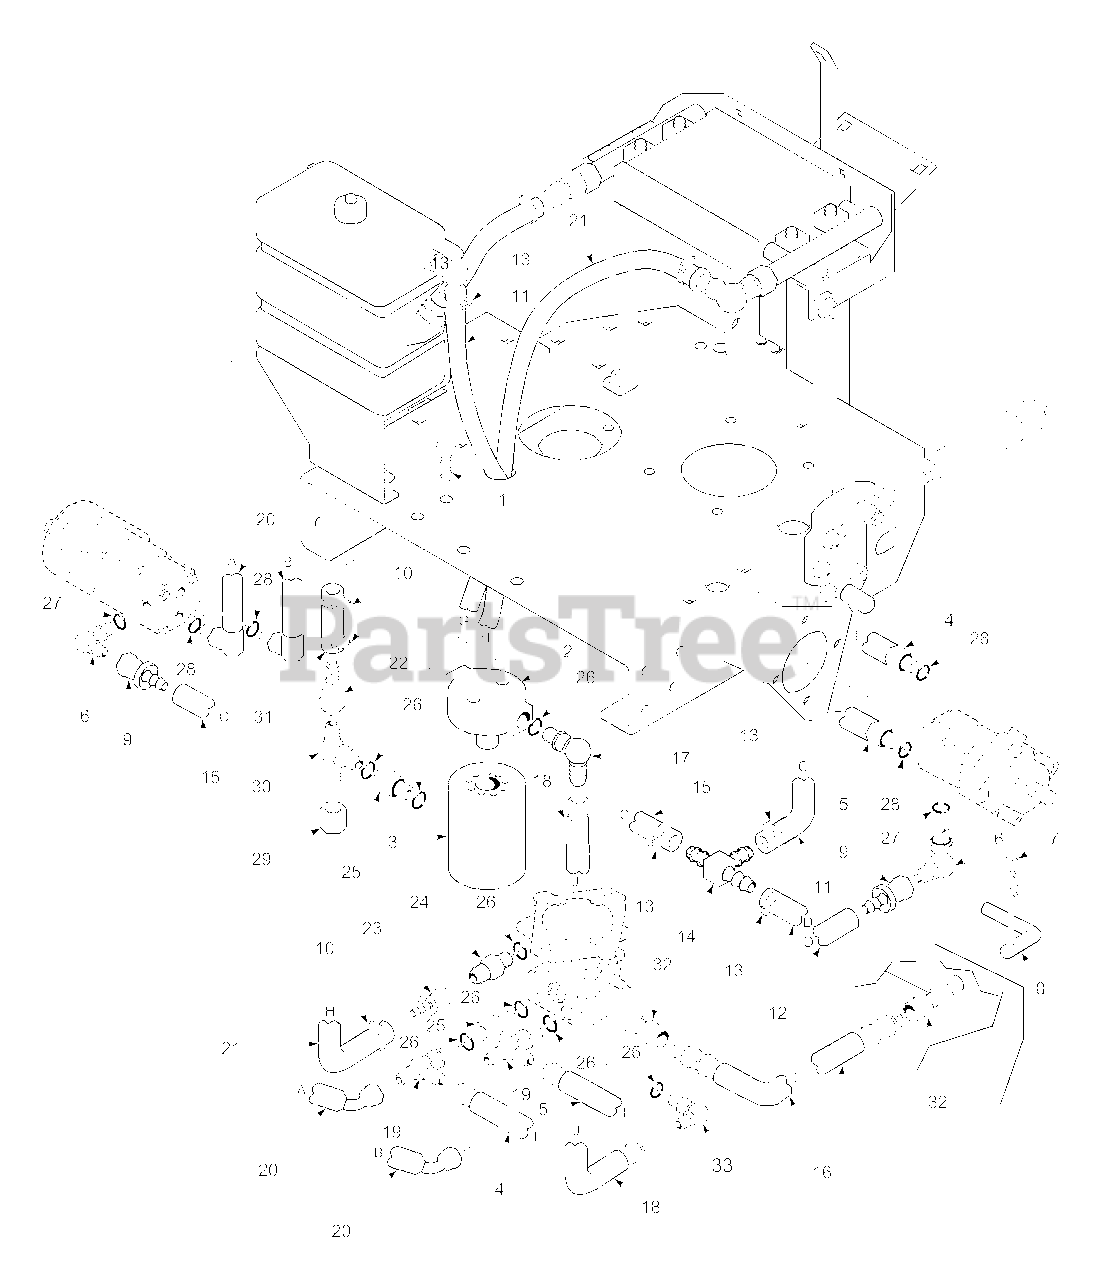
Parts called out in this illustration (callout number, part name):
1	Capscrew, 1/4-20 x 1/2 Serr. Fl. Hex Head
2	Filter Head
3	Filter, Spin-On Lube
4	Hose Assembly
5	Hose Assembly
6	Elbow, 90 Degrees
7	Hairpin Cotter
8	Lever, Dump Valve
9	Connector, Flare Swivel with Hose Barb
10	Hose Clamp
11	Hose, 1/4 Pushlock
12	Hose, 1/4 Pushlock
13	Hose Clamp
14	Tee Union, Pushlock Hose
15	Hose, 1/4 Pushlock
16	Hose, Dump Valve
17	Elbow, 90 Deg.
18	Inlet Hose, 3/4" ID
19	Tee, 1/2" Run
20	Motor Hose
21	Hose, Pump To Oil Cooler
22	Coupling, Flare Swivel
23	Coupling, Flare Swivel With Barb
24	Tube Union
25	O-Ring Bushing
26	O-Ring
27	O-Ring
28	O-Ring
30	Tee, Jic to O-Ring
31	Hose
32	Compression Fitting
33	Elbow, 90 Deg.
